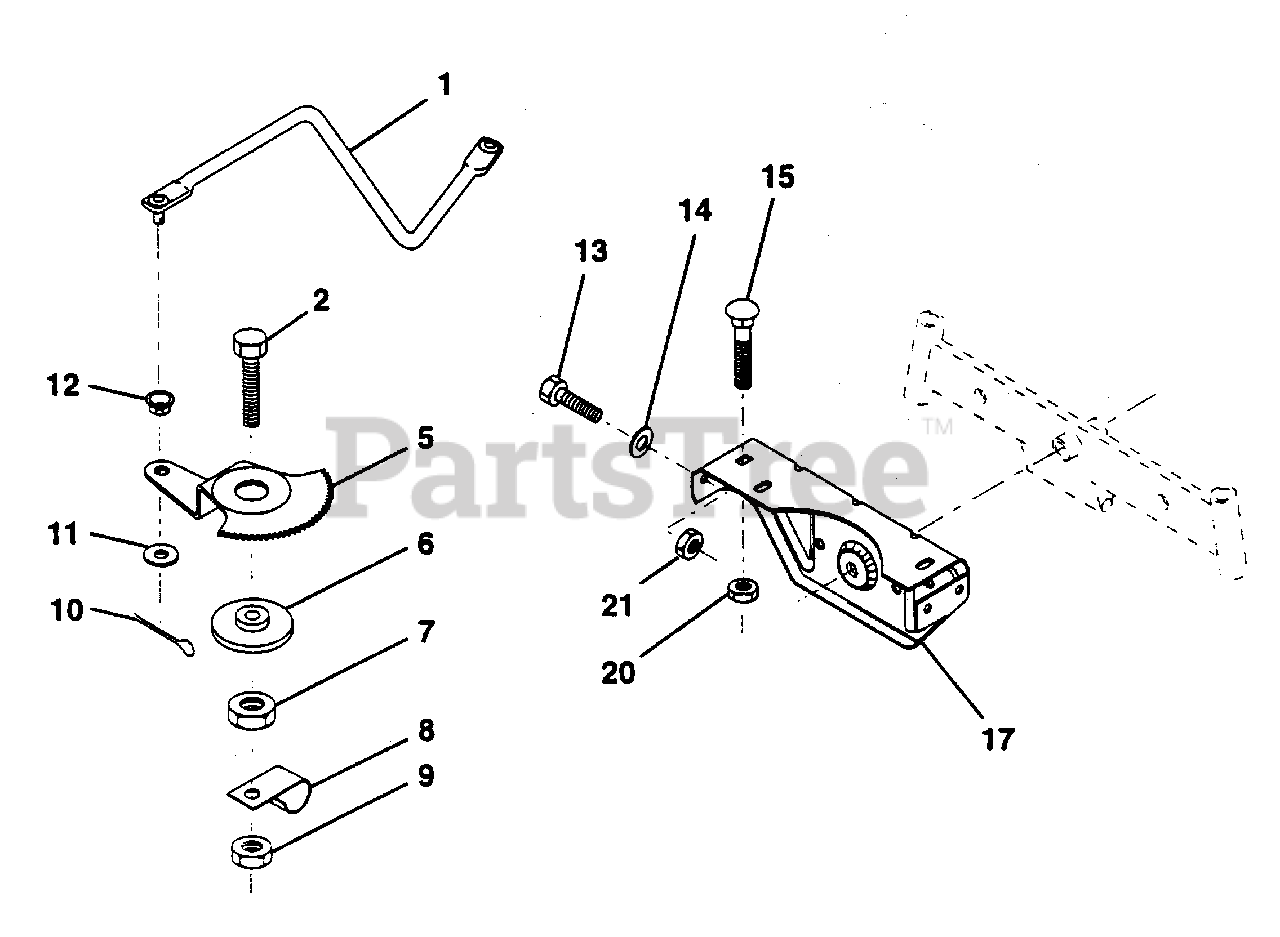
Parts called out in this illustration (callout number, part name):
1	Link, Drag (AYP part number)
2	Bolt, Fin Hex 1/2-13 x 1-3/4 (AYP part number)
5	Gear, Sector (AYP part number)
6	Bushing (AYP part number)
7	Nut, Heavy Hex Top Lock 1/2-13 UNC (AYP part number)
8	Clip, Insulated (AYP part number)
9	Nut, Crownlock 3/8-16 (AYP part number)
10	Pin, Cotter 1/8 x 3/4 (AYP part number)
11	Washer, 13/32 x 13/16 x 16 Ga. (AYP part number)
12	Bushing (AYP part number)
13	Bolt, Hex Hd. 5/16-18 UNC x 3/4 (AYP part number)
14	Washer 11/32 x 7/8 x 16 Ga. (AYP part number)
15	Bolt, Carriage 3/8-16 UNC x 3/4 (AYP part number)
17	Support, Front Axle (AYP part number)
20	Nut, Lock Hex w/Wsh. 3/8-16 (AYP part number)
21	Nut, Lock Hex w/Ins. 5/16-18 (AYP part number)
